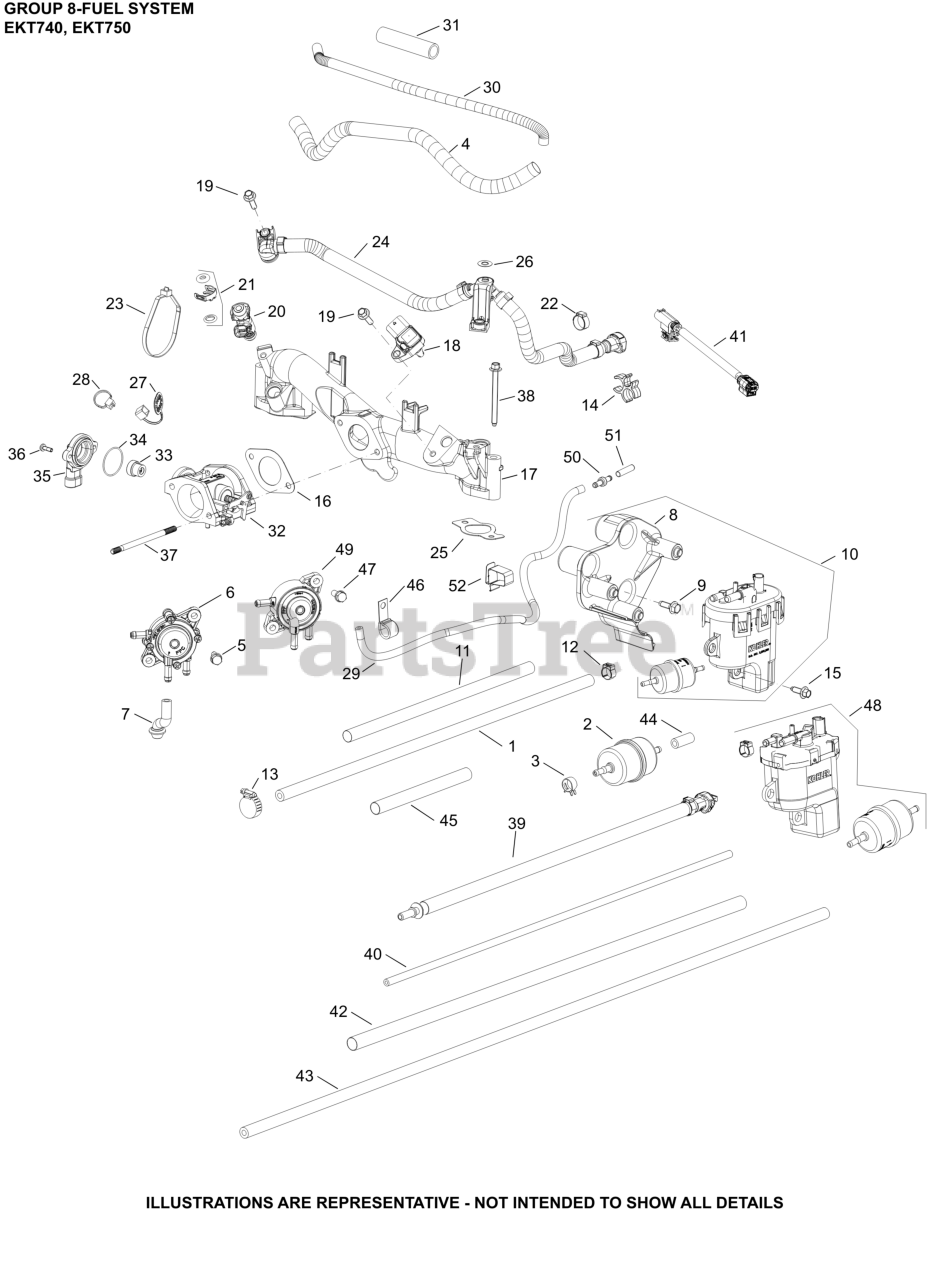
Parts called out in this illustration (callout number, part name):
2	FILTER, FUEL
3	SPRING CLAMP, HOSE
4	SLEEVE, ANTI ABRASION
8	BAFFLE, FUEL MODULE
9	SCREW, THREAD FORMING
11	SLEEVE, INSULATING
12	CLAMP, OETIKER
14	RETAINER, HOSE
15	SCREW, HEX FLANGE (M6 W/DOG POINT)
16	GASKET, THROTTLE BODY
17	MANIFOLD MACHINED (EFI)
18	SENSOR, T-MAP
19	SCREW, FLG M6x1.0x20
20	INJECTOR, FUEL
21	KIT, FUEL INJECTOR O-RING
22	CLAMP, HOSE
24	FUEL HOSE ASSY(ECV,FCV,EZT,EKT,PCH,PCV)
25	KIT, INTAKE MANIFOLD GASKET
26	CLIP, RETAINER
27	CAP, CONNECTOR
28	TIE, CABLE
29	HOSE, EVAPORATIVE 20"- (#24326143S)
30	SLEEVE, ANTI-ABRASION
31	SLEEVE, CORRUGATED
32	BODY ASSEMBLY, THROTTLE W/TPS
33	MAGNET, TPS SENSOR
34	O-RING, TPS SENSOR
35	SENSOR, THROTTLE POSITION
37	STUD-USE 25 072 48-S
38	SCREW, HEX FLANGE (M6 W/DOG POINT)
47	SCREW, HEX HEAD
48	KIT, FUEL PUMP MODULE
49	PUMP, FUEL (PULSE)
50	FITTING, FUEL SYSTEM
51	CAP, MASKING
52	CLIP, BLOWER HOUSING
